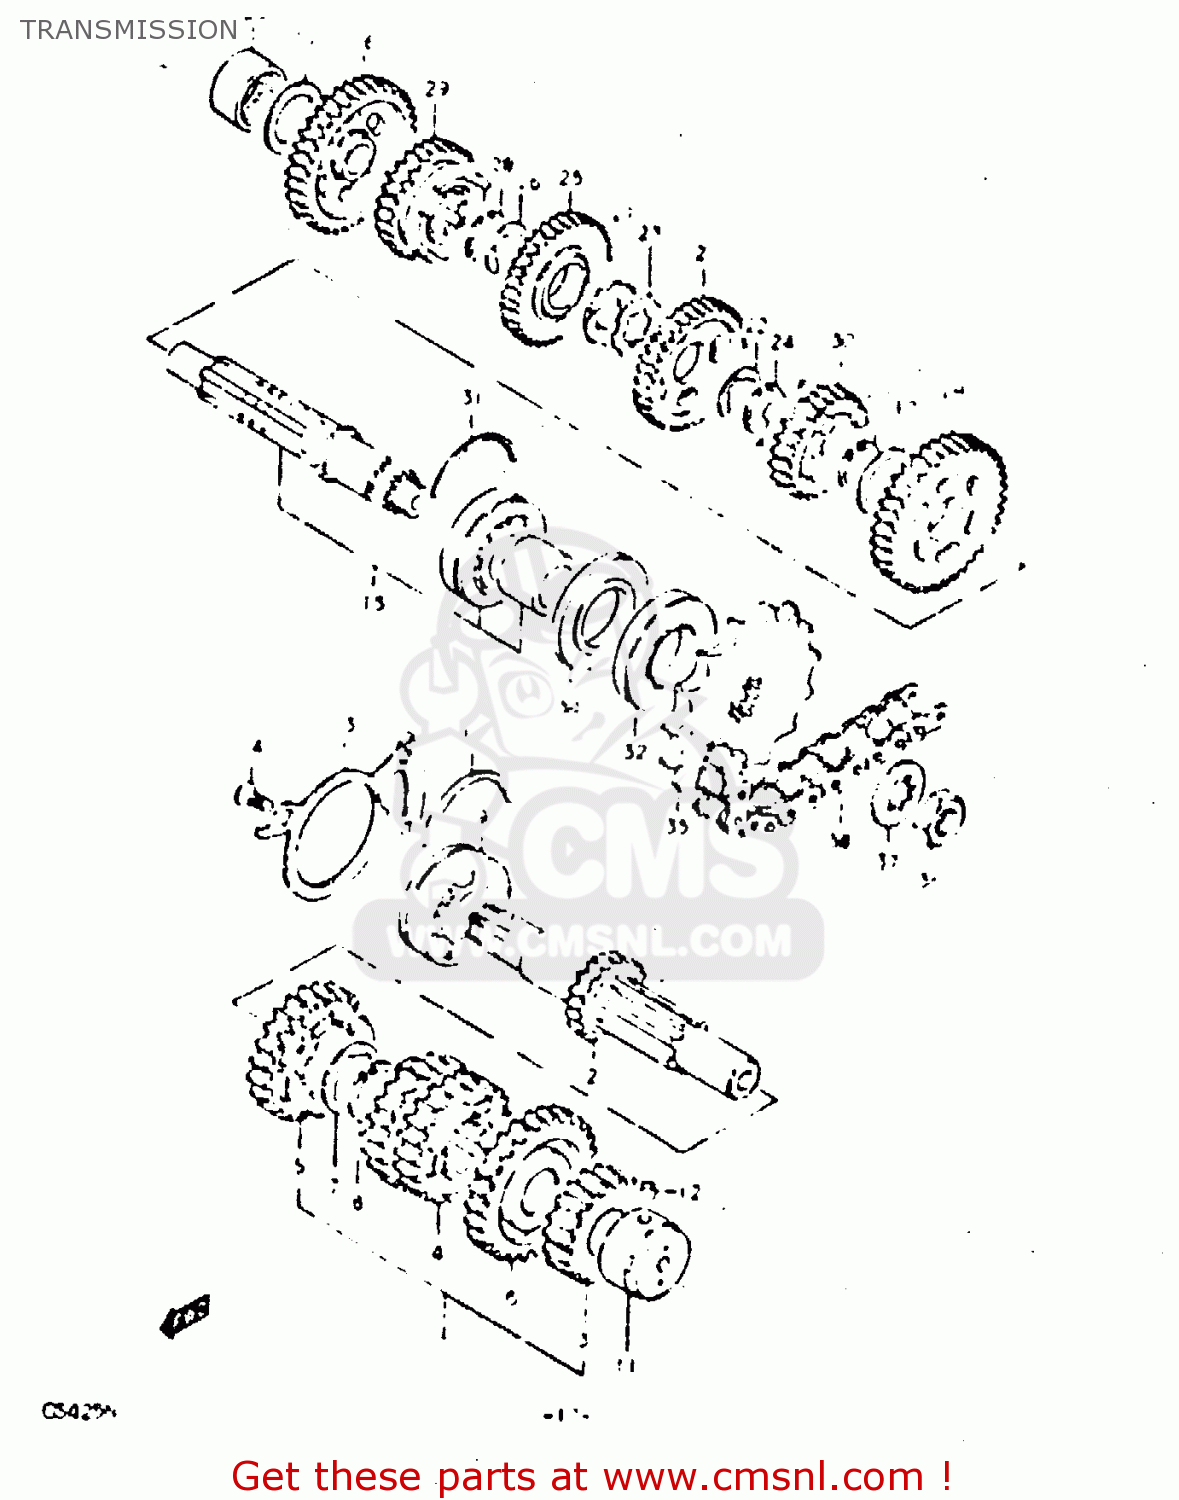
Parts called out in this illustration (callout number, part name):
1	SHAFT,COUNTER
2	SHAFT,COUNTER
3	GEAR,2ND DRIVE(NT:18)
4	GEAR,THIRD DRIVE
5	GEAR,FIFTH DRIVE
6	GEAR,SIXTH DRIVE
7	WASHER
8	CIRCLIP
9	BEARING(25X62X17)
10	C-RING
11	ROLLER BEARING (20X34X2
12	PIN
13	PLATE,COUNTERSHAFT BEARING
14	SCREW
15	SHAFT,DRIVE
16	GEAR,FIRST DRIVEN
17	WASHER
18	GEAR,SECOND DRIVEN
19	WASHER
20	CIRCLIP
21	GEAR,THIRD DRIVEN
22	WASHER,LOCK
23	WASHER,LOCK
24	CIRCLIP
25	GEAR,FOURTH DRIVEN
26	WASHER,LOCK
27	WASHER
28	CIRCLIP
29	GEAR,5TH DRIVEN(NT:25)
30	GEAR,SIXTH DRIVEN
31	C-RING
32	OIL SEAL
33	ROLLER BEARING (20X34X1
34	SEAL,OIL(32X62X5.5)
35	SPROCKET,ENGINE(NT:16)
36	NUT
37	WASHER
38	CHAIN ASSEMBLY,DRIVE
